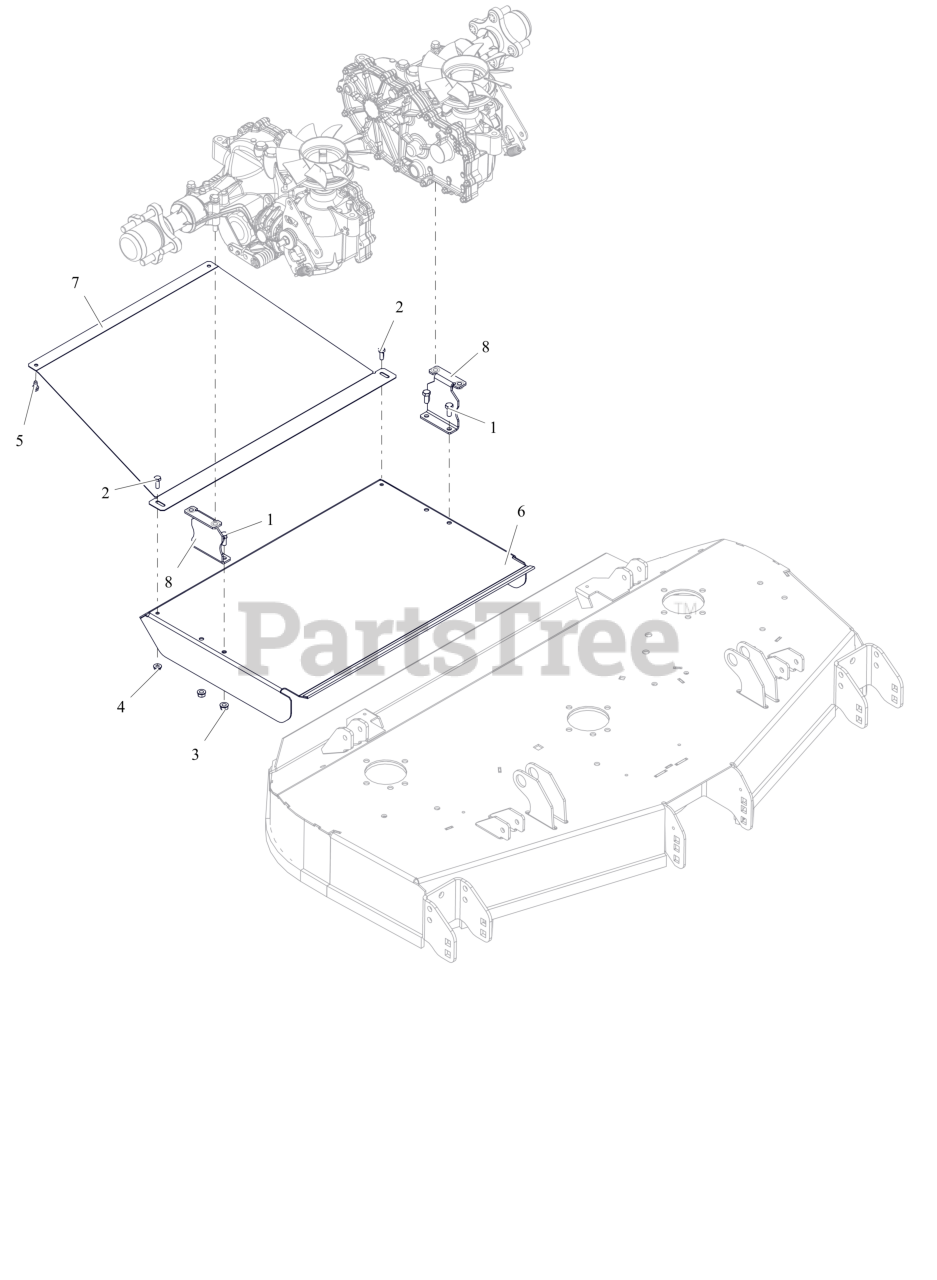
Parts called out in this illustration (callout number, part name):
1	BLT,HEX .31-18X.75 G5 ZCC
2	BLT, HEX .25-20X.75 G5 ZCC
3	NUT,LK-CTR-FLG .31-18 GF ZCC
4	NUT-LK-TOP-FLG .250-20 GF ZCC
5	SCR-TAP .25-20X.50 HWH ZCC
6	DEFLECTOR, TRANSAXLE APEX
7	DEFLECTOR, UNDERBODY
8	BRKT, DEFLECTOR SUPPORT
